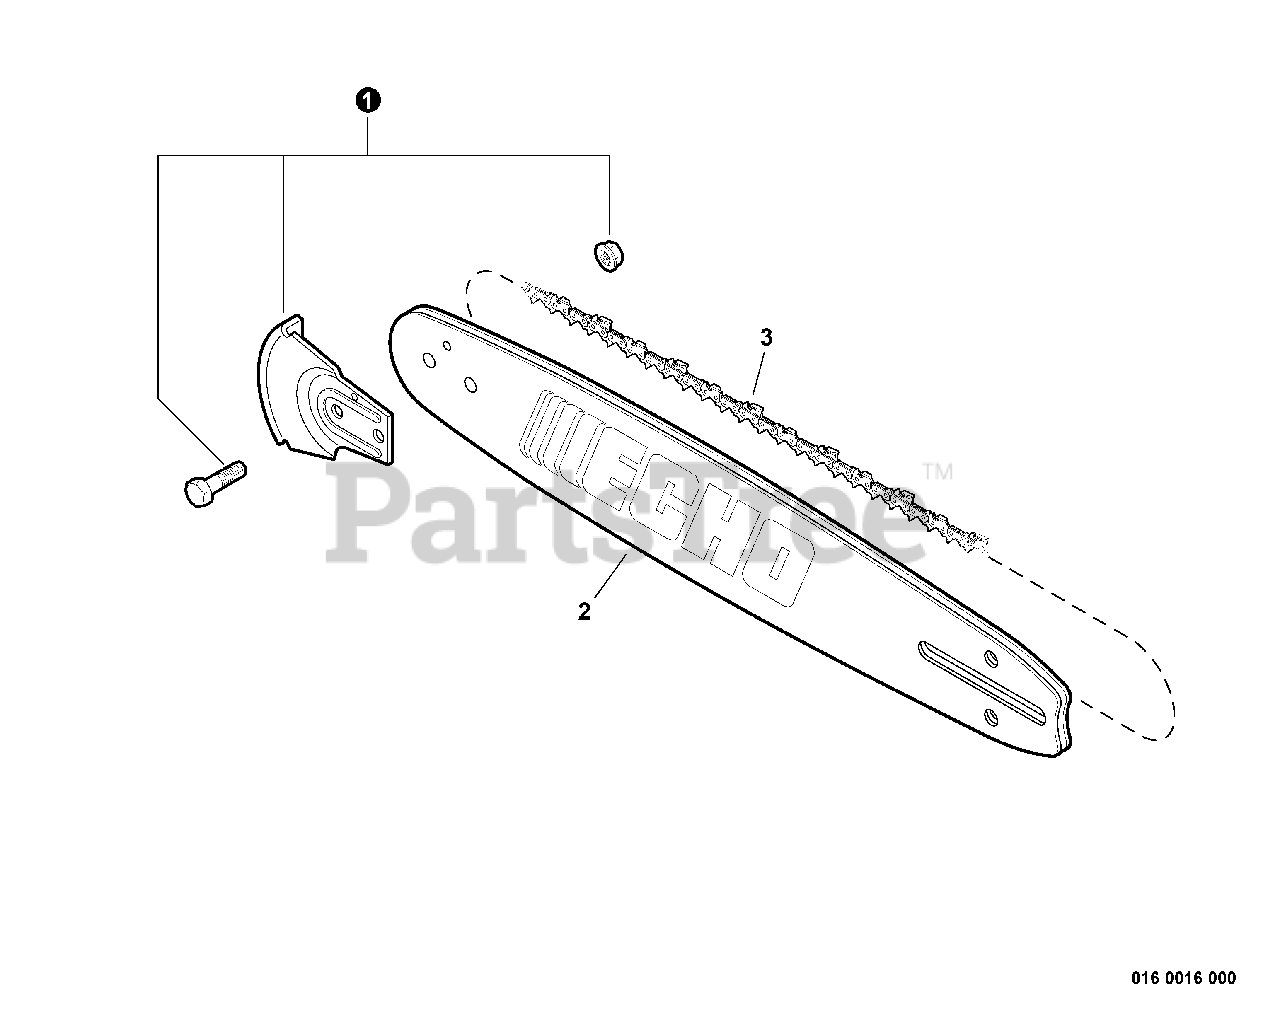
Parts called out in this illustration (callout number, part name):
1	KICK GUARD KIT
2	GUIDE BAR, 18" DOUBLE-GUARD
3	SAWING CHAIN - 18" -- PRO GUARD
